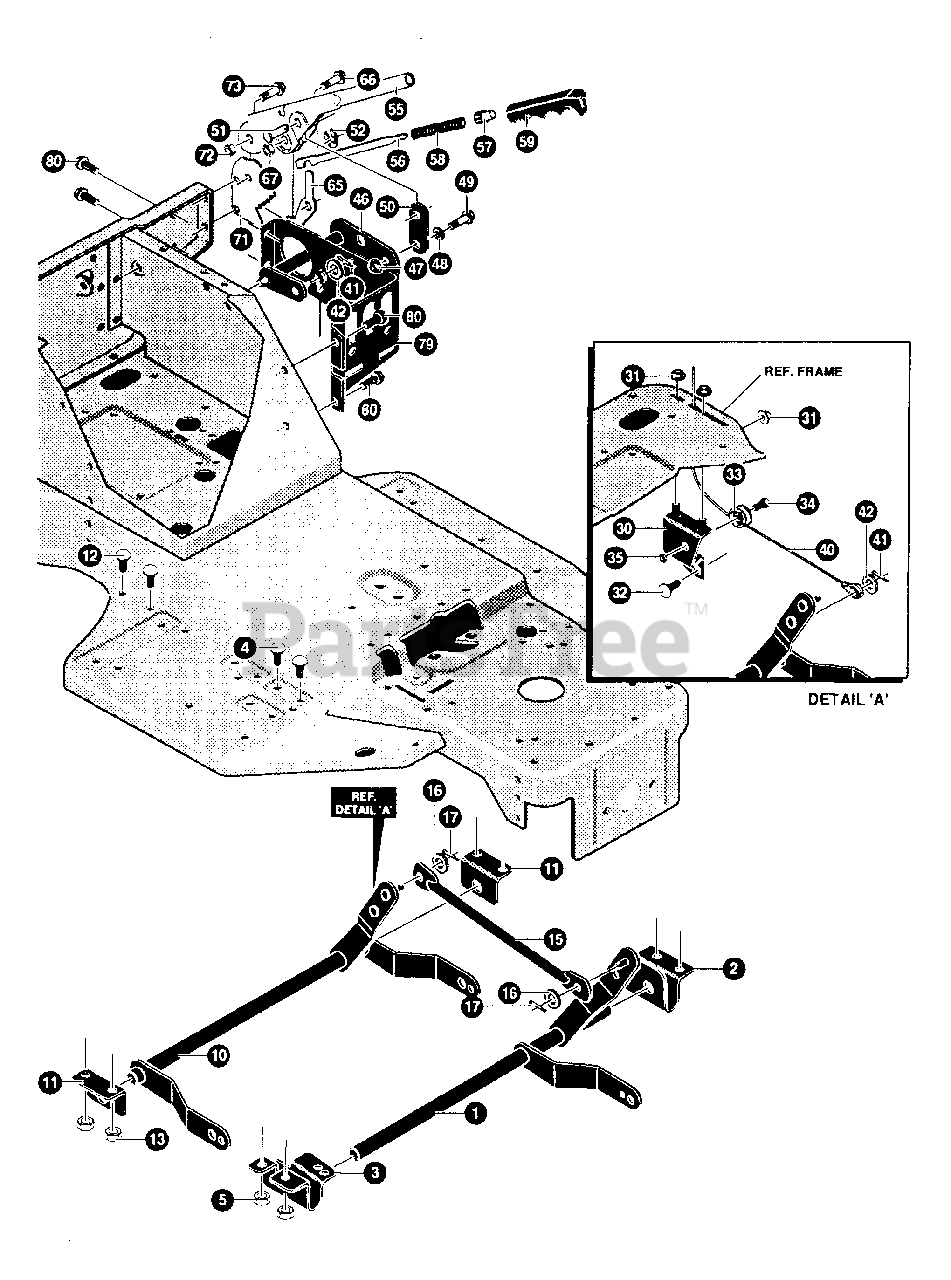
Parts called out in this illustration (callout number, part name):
1	SHAFT, ASSY FRONT LIFT EURO
2	BRACKET, FRONT HANGER RH
3	BRACKET, FRONT HANGER LH
4	SCREW, 5/16-18X.75 HHC
5	NUT 5/16-18 REGHEXCTRLK
10	SHAFT, ASSY REARLIFT E/C EUR
11	BRACKET, REAR HANGER EURO
12	SCREW, 5/16-18X.75 HHC
13	NUT, 5/16-18 REGHEXCTRLK
16	WASHER, FLAT .406X.81X.065
17	PIN, COTTER .090 DIAX.75LG
30	ASSY,PULLEY BRKT
31	NUT, 5/16-18 HXWDFLLK
32	BOLT, 5/16-18X.63 CARRLN
33	PULLEY, POWDER METAL
34	BOLT, .375X.700 HHSH 5/16-18
35	NUT, 5/16-18 REGHEXCTRLK
40	CABLE,DECK LIFT
41	PIN, COTTER .090 DIAX.75LG
42	WASHER, FLAT .344X.69X.065
46	ASSY UPPER SHAFT
47	NUT, 5/16-18 REGHEXCTRLK
48	WASHER, FLAT .333X.87X.119
49	BOLT, .375X.500 HHSH 5/16-18
51	PIN,CLEVIS .310DIA+.475LG
52	RING RET E .31 X .25TRUX5133-31
55	HEIGHT LEVER
56	ROD ACTUATOR
57	KNOB HEIGHT ADJ PUSH BUTTON
58	SPRING HEIGHT ADJUST
59	GRIP, HAND .741DX5.15
65	PAWL SQUARE
66	BOLT, .500X.270 HHSH 5/16-18
67	NUT, 5/16-18 HWDFLCTRLK
71	QUADRANT
72	NUT 5/16-18 REGHEXCTRLK
73	BOLT, .500X.270 HHSH 5/16-18
79	BRACKET SUPPORT ENGAGE
80	SCREW 5/16-18X.50 WAHHTAP
